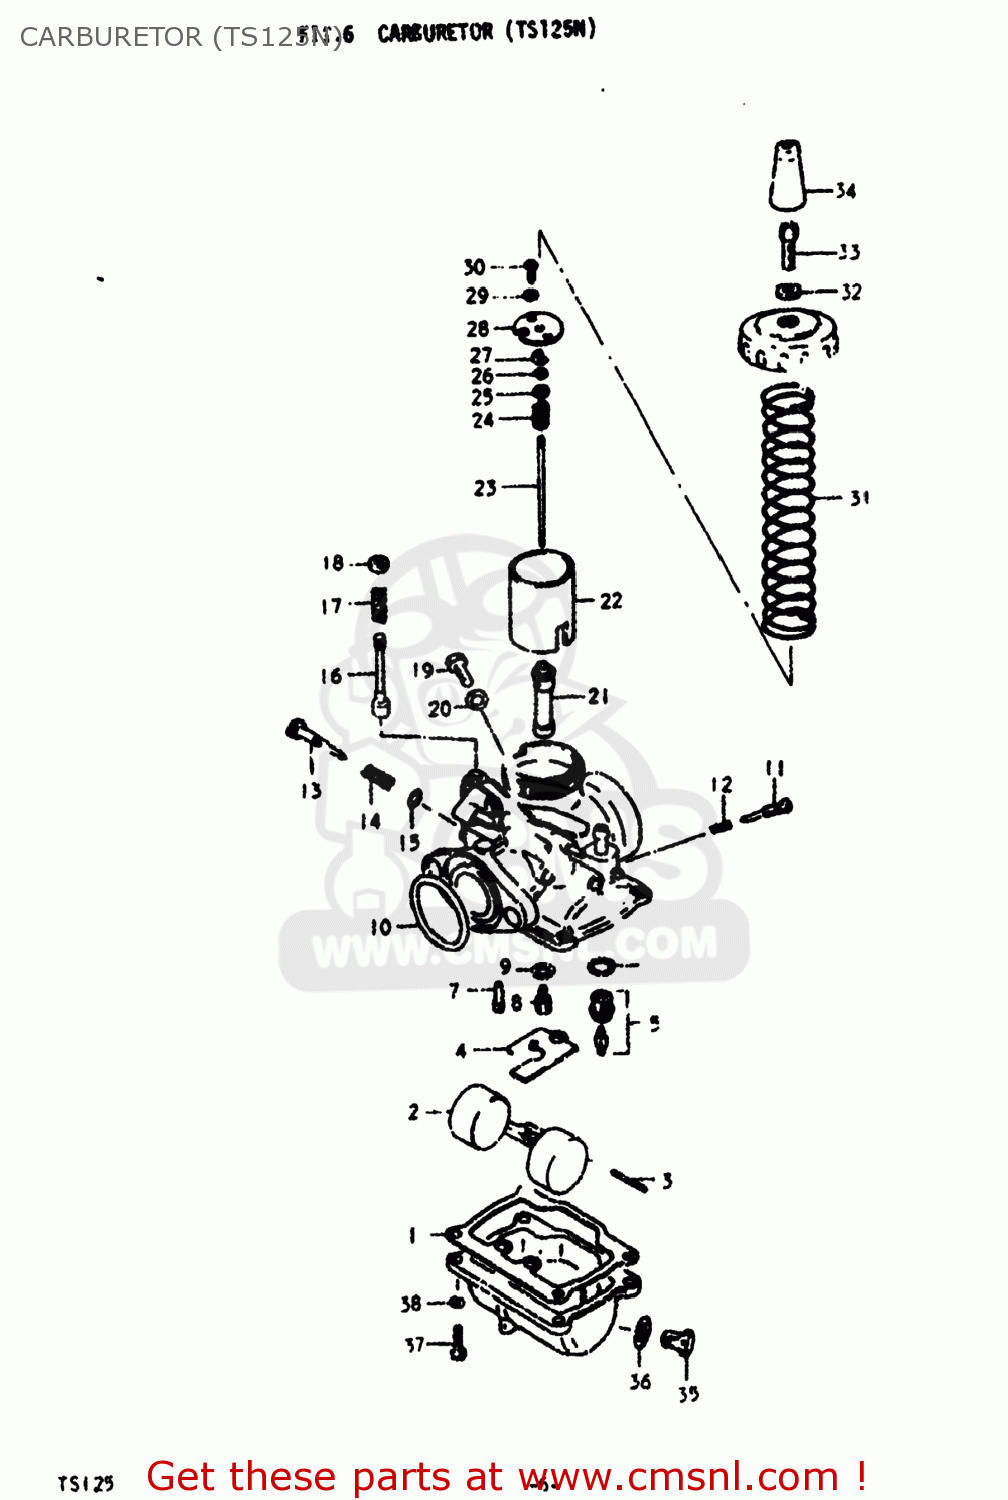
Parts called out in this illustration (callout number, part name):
1	GASKET,FLOAT CHAMBER (NAS)
2	FLOAT
3	PIN,FLOAT
4	PLATE
5	VALVE ASSY,NEEDLE
6	GASKET,VALVE SEAT (NAS)
7	JET,PILOT(17.5)
8	JET,MAIN
9	WASHER
10	O RING
11	SCREW,PILOT AIR
12	SPRING
13	SCREW,THROTTLE STOP
14	SPRING,PILOT
15	O-RING
16	VALVE,STARTER
17	SPRING
18	RUBBER,THROTTLE VALVE CAP
19	BOLT
20	GASKET,THRO VALVE INSPECTION (NAS)
21	JET,NEEDLE
22	VALVE,THROTTLE
23	NEEDLE JET
24	SPRING
25	WASHER,JET NEEDLE
26	CLIP
27	RING
28	PLATE,THROTTLE VALVE
29	LOCK WASHER
30	SCREW
31	SPRING,THROTTLE VALVE
32	NUT
33	ADJUSTER,CABLE
34	CAP
35	PLUG
36	GASKET,DRAIN,PLUG (NAS)
37	SCREW
38	LOCK WASHER
